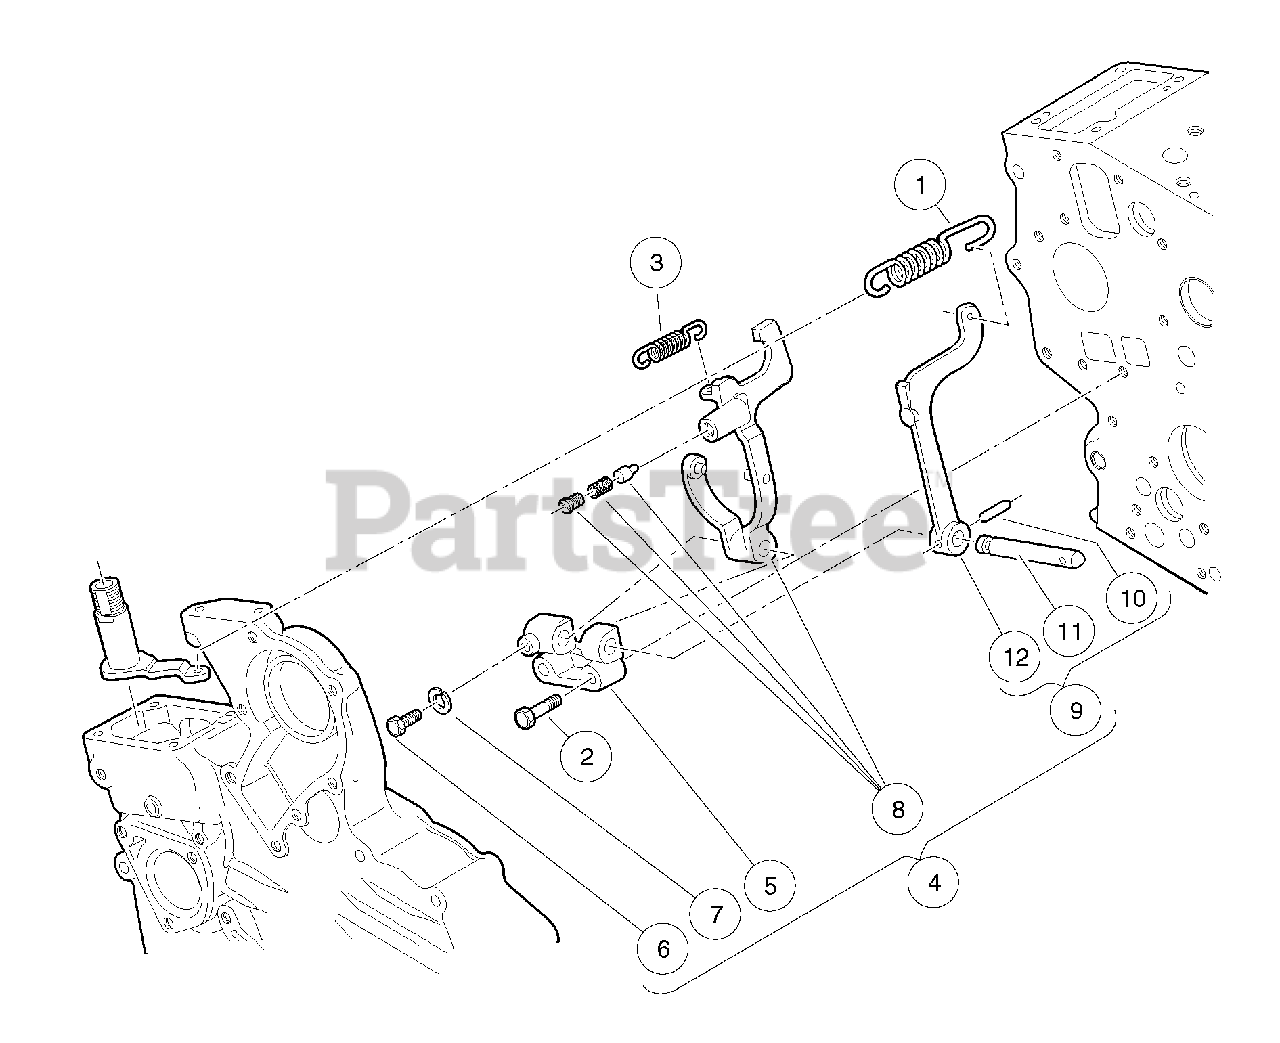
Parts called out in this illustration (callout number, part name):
1	Spring, Governor
2	Bolt, M5 X 0.75 X 25
3	Spring, Start
4	Assembly, Governor Fork
5	Holder, Fork Lever
6	Bolt, M5 X 0.75 X 11
7	Washer, Spring, M5
8	Lever, Fork, Middle, D722 CB
9	Assembly, Governor Fork Level, Lower, D722 CB
10	Pin, Spring
11	Shaft, Fork Lever
12	Lever, Fork, End, D722 CB
